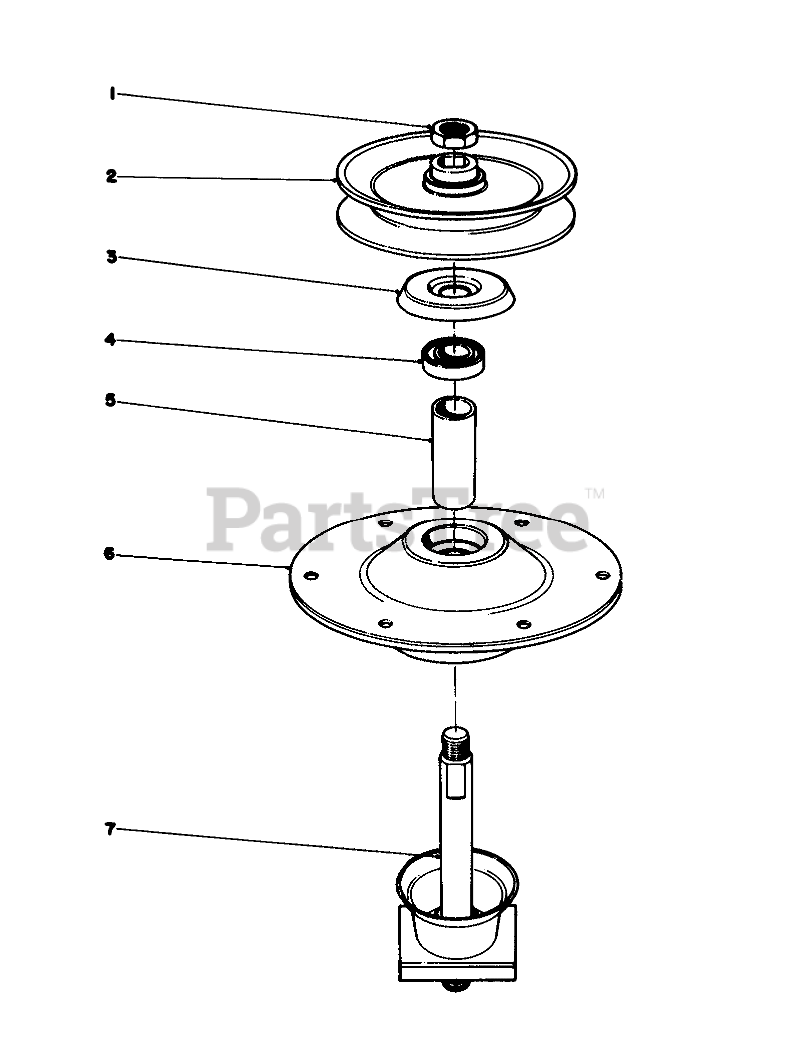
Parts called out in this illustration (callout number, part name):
1	Locknut
2	PULLEY B
3	COVER-DUST
4	BEARING
5	SPACER
6	Housing
7	SHAFT & SADDLE ASM
